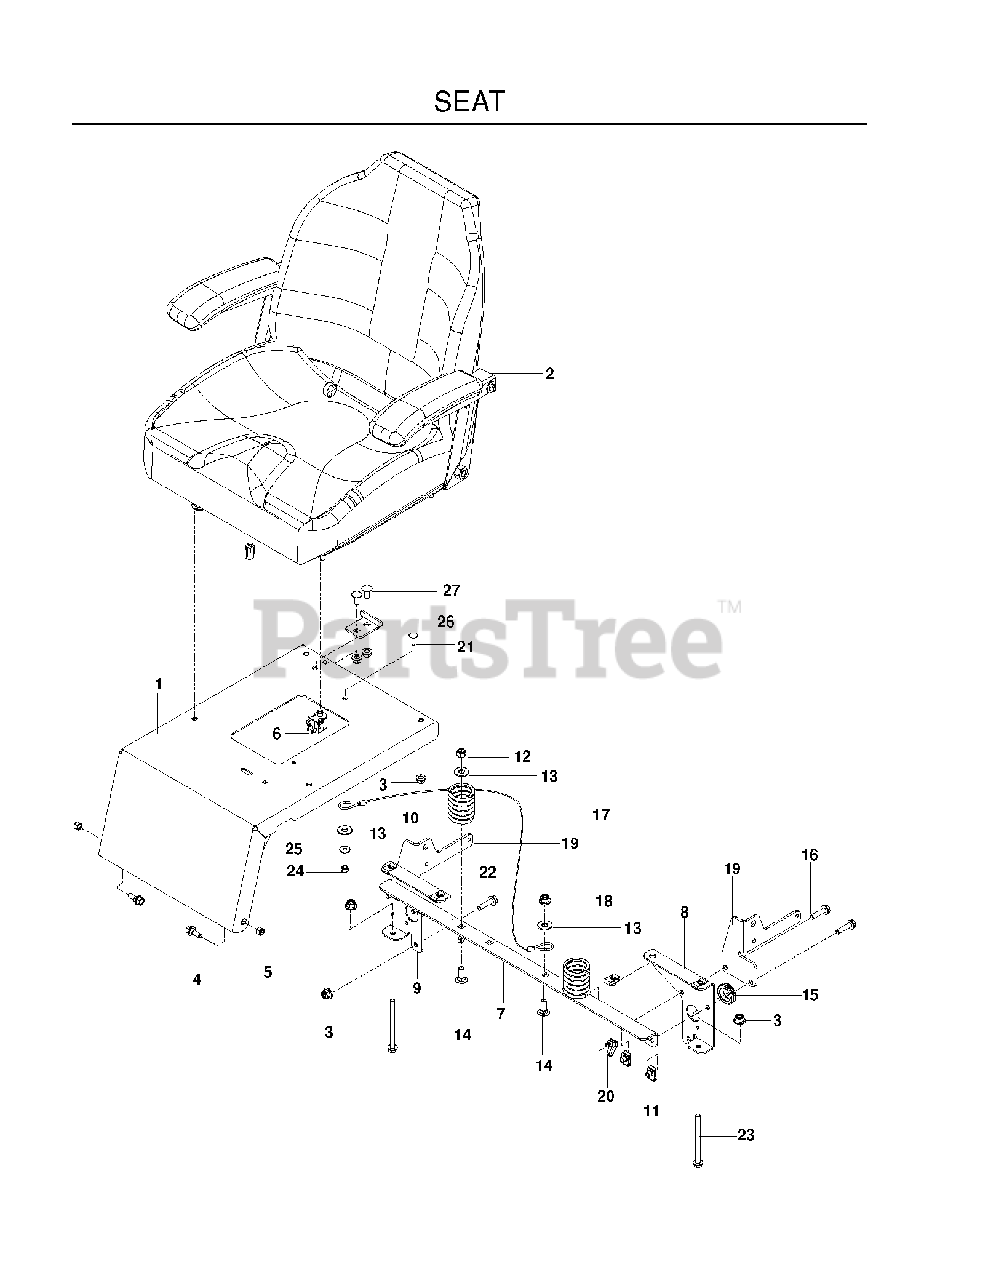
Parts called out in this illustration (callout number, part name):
1	SEAT MOUNT, W/DECALS
3	5/16-18 NYLOC FLANGE NUT
4	SB 5/16-18 HEX HD GD5, BLK ZN
5	NUT 5/16 NYLOC
6	SEAT SWITCH
7	SUPPORT, SEAT
8	SUPPORT, LT, BLK
9	SUPPORT, RT, BLK
10	SPRING, SEAT
11	U-CLIP 5/16-18 NUT RETAINER
12	NUT 3/8-16 NYLOC
13	WASHER 3/8 FLAT
14	RHSNB 3/8C X 1
15	RUBBER GROMMET
16	HHFS 5/16-18 X 1.25 TPBLT GD 5
17	SEAT LANYARD
18	NUT 3/8-16 HEX FLG NYLOC ZD
19	MOUNT, SEAT BELT, BLACK
20	TIE WRAP, 8-3/8", W/CLIP
21	RHSNB 1/4C X 3/4
22	BLT 5/16-18 X 1 THRD FORM ZD
23	HHFS 5/16-18 X 3 3/4
24	NUT 1/4-20 NYLOC
25	WASHER 1/4 FLAT
26	STOP, SEAT - BLACK
27	RHSNB 5/16-18 X 3/4
